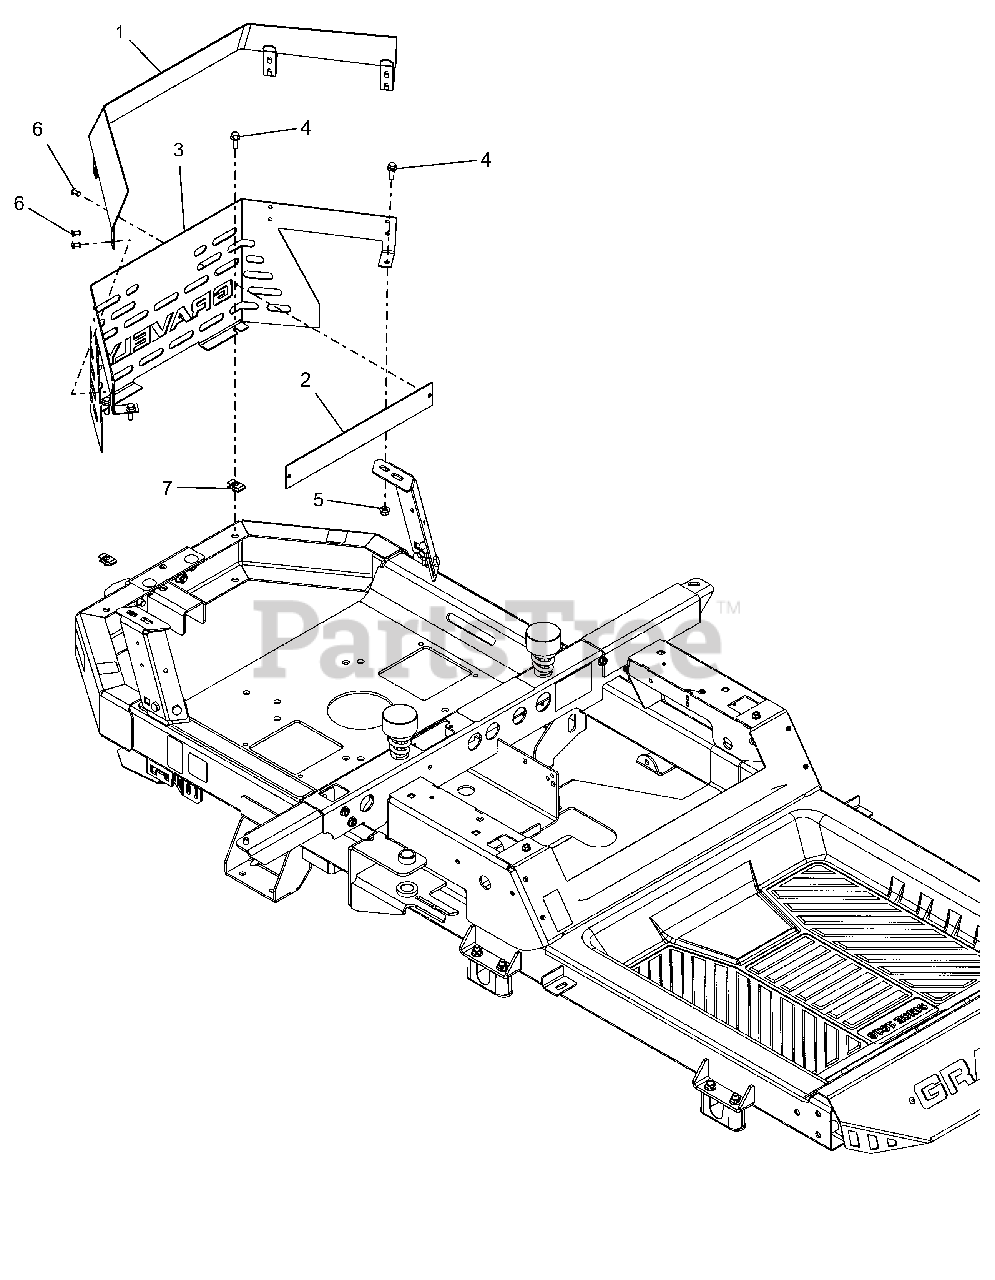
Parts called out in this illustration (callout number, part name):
1	BRACKET, ENGINE SHROUD TRIM
2	PLATE, SHROUD BACKER
3	SHROUD, ENGINE GRAVELY
4	BLT,HEX-FLG .25-20X.75 G5 BFP
5	@NUT-LK-TOP-FLG .25-20 YWZC
6	RIVET, #66 STEEL POP PD BLACK
7	NUT-RTNR .25-20X.56
